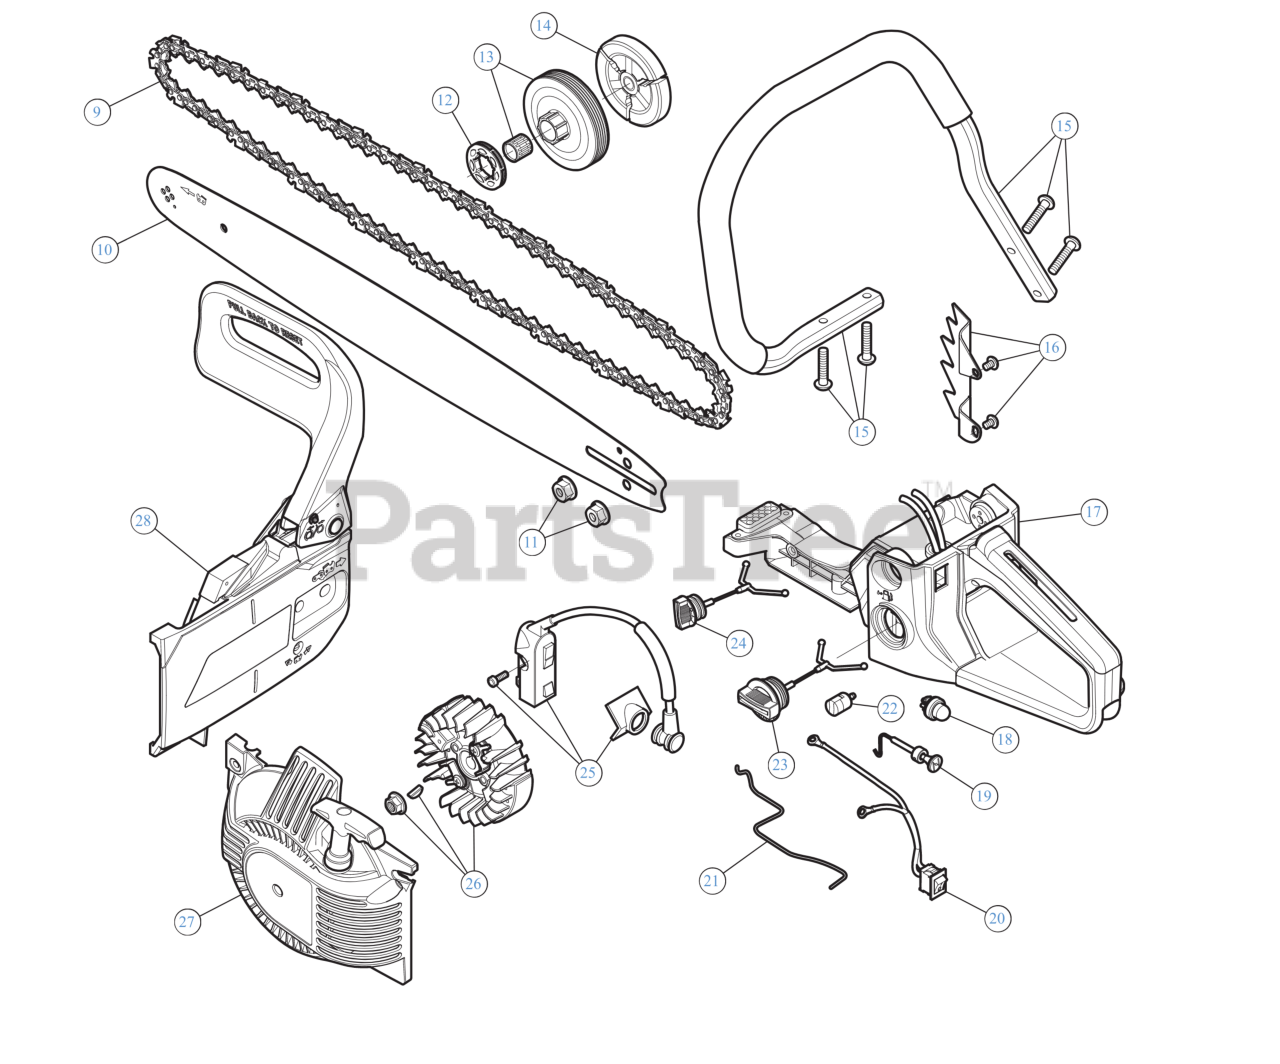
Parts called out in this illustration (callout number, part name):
9	20" CHAINSAW CHAIN
10	20" BAR
11	BAR NUT M8
12	SPROCKET
13	CLUTCH DRUM ASSEMBLY
14	CLUTCH ASSEMBLY
15	HANDLE ASSEMBLY
16	SPIKE PLATE W/HDW
17	FUEL HOUSING ASSEMBLY
18	PRIMER BULB YD2500-18410
19	CHOKE LEVER ASSEMBLY
20	SWITCH ASSEMBLY
21	THROTTLE ROD
22	FUEL FILTER YD4600-18034
23	FUEL CAP ASSEMBLY SRS
24	OIL CAP ASSEMBLY
25	MODULE
26	FLYWHEEL
27	RECOIL ASSEMBLY (SBD4620YD4620.8CM-25313)
28	BRAKE ASSEMBLY (SBD4620 YD4620.8CM-27724)
